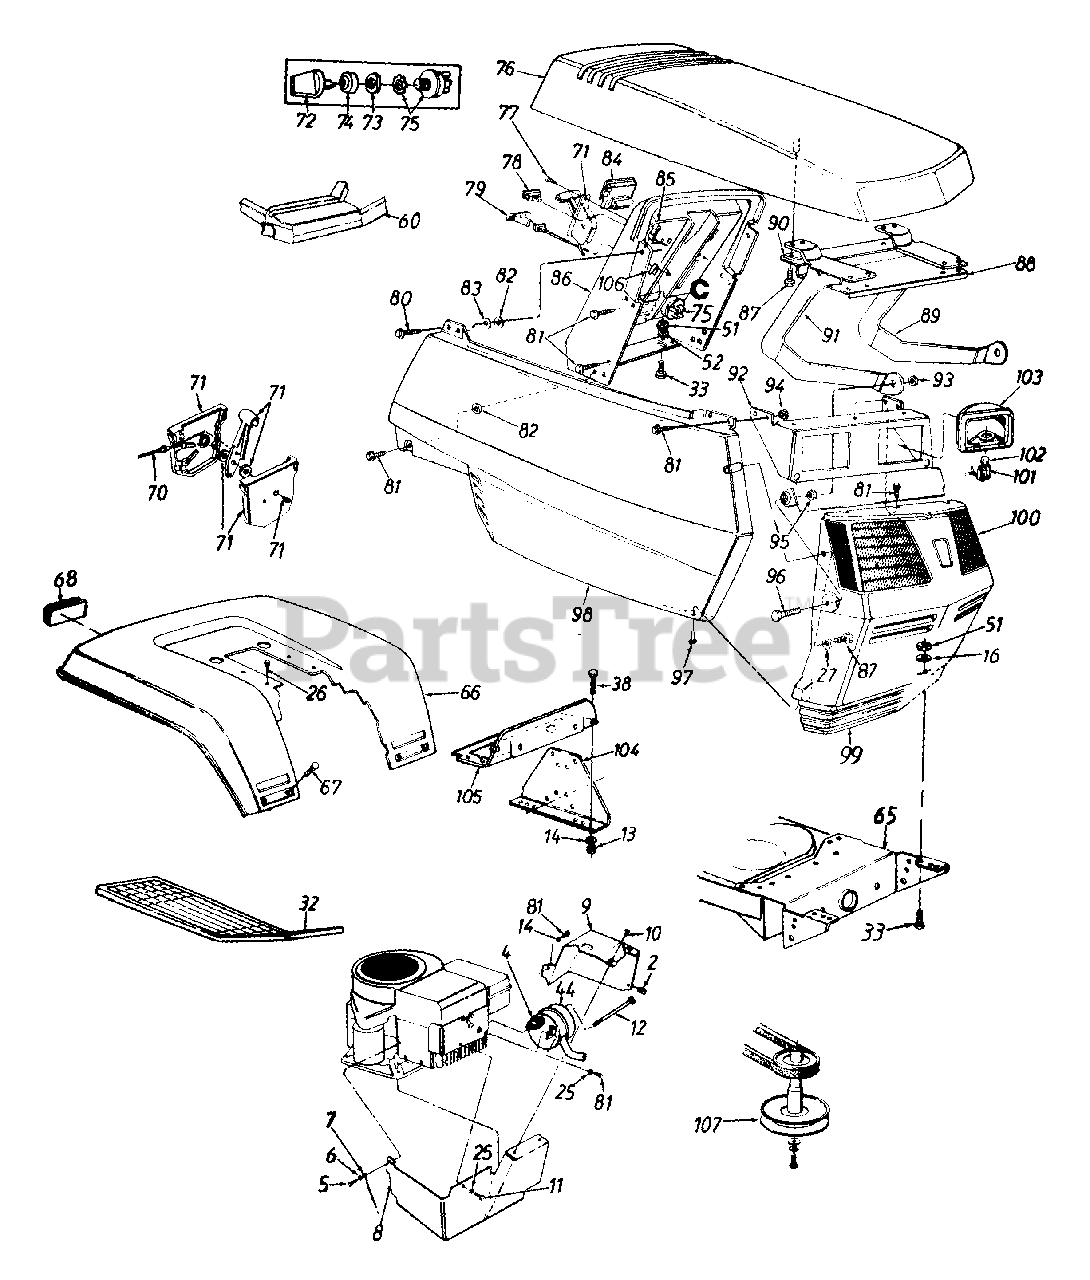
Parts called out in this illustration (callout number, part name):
2	Speed Nut #10-24 Thd.
4	Gaskets
5	Truss Mach. Scr. 5/16-18 x .75"
6	External L-Wash. 5/16" I.D.
7	Ground Wire
8	Muffler Heat Shield - Front
9	Muffler Heat Shield - L.H.
10	Hex Wash. Tap Scr. #10 x .5" L.g.
11	Hex Bolt 1/4-20 x 3/8" Lg.
12	Shld. Bolt 7/16" Dia. x 3-5/8"
13	Hex Nut 1/4-20 Thd.
14	L-Wash, 1/4" I.D.
16	Fl-Wash. .344" I.D. x 1" O.D.
25	Spr. Wash. .265" I.D.
26	Hex Wash. Hd. AB-Tap Scr. 5/16 x .75" Lg.
27	Fl-Wash. .218" I.D. x .5" O.D.
32	Rubber Foot Pad - L.H.
33	Hex Bolt 5/16-18 x .75" Lg.
38	Hex Bolt 1/4-20 x .62" Lg.
44	Muffler
51	Hex Nut 5/16-18 Thd.
52	Ft-Wash. .343" I.D. x .687"
60	Steering Wheel Insert
68	Reflector
70	Throttle Wire 18.5" Lg.
71	Throttle Control Box Ass'y.
72	Ignition Key
73	Ignition Switch Nut
74	Ignition Switch Cap
75	Ignition Switch
76	Hood (Yellow)
77	Truss Mach. AB-Tap Scr. #10 x .5" Lg.
78	Light Switch
79	Choke Control
80	Hex Wash. Hd. Tap Scr. 1/4 x .75" Lg.
81	Hex Tap Scr. 1/4-20 x .5" Lg.
82	Push Nut Fastener
83	Fl-Wash. .27" I.D. x .948"
84	Ammeter
85	Speed Nut 1/4-20 Thd.
86	Dash Panel
87	Hex Wash. Hd. B-Tap Scr. 1/4 x .62" Lg.
88	Hood Reinforcement
89	Hood Hinge - L.H.
94	Hex L-Nut 1/4-20 Thd.
95	Hex Jam Nut 5/16-18 Thd.
96	Hex Bolt 5/16-18 x 7/8" Lg.
97	Truss Mach. B-Tap Scr. #10 x .5" Lg.
98	Side Cover - R.H. (Yellow)
99	Grille (Yellow)
101	Twist Lock - Lamp Socket
102	Lamp
103	Headlight Housing
107	Engine Pulley (30" Deck Only)
